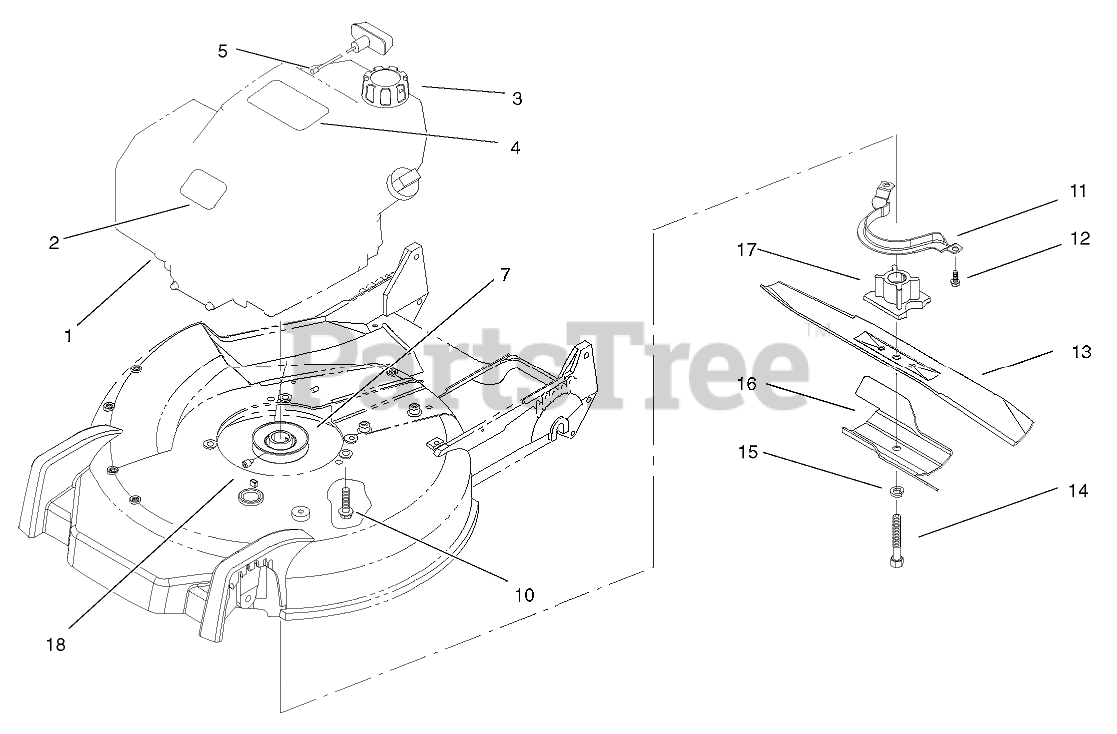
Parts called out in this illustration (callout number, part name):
2	PLATE-LOGO
3	CAP-GAS
4	DECAL-ENGINE
5	STOP-ROPE
7	PULLEY ASM
10	SCREW-HWH
11	GUIDE-BELT
12	SCREW-HWHTF
13	Blade
14	SCREW-BLADE
15	WASHER-LOCK
16	ACCELERATOR-BLADE
17	RETAINER-BLADE
18	SCREW-SET
